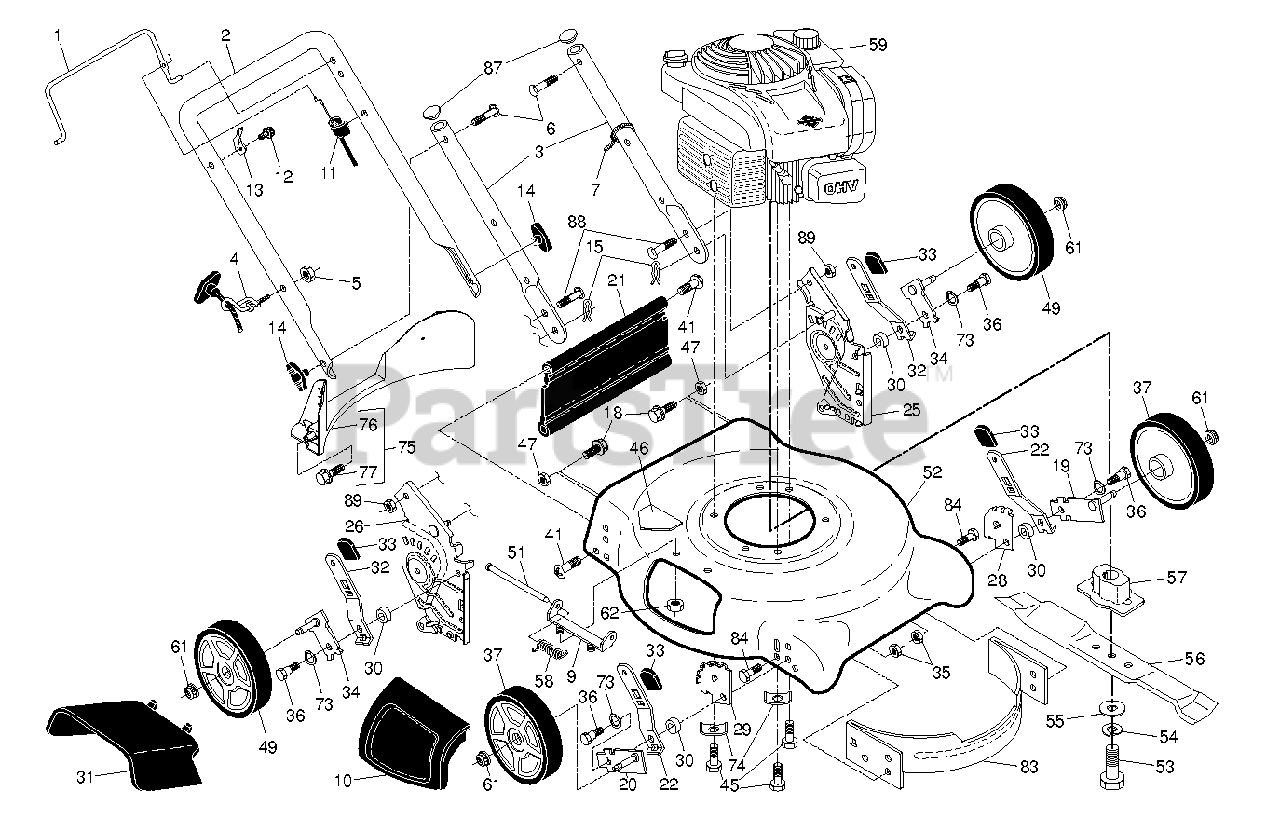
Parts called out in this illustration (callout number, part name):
1	BAIL.CONT.D.STRAIGHT.PUSH.BLK
2	HANDLE.UPPER.ECONOMY.BLACK
3	HANDLE.LOWER.DOME.BT.BLACK
4	Rope Guide, Blk Zinc Chrom
5	T-KNOB.NEW ROPE GUIDE
6	BOLT, HANDLE 5/16-18X1.75
7	TIE GUIDE
9	BRACKET.ASM.HOUSING.EZ.MUL
10	MULCH DOOR
11	CABLE.MZR.RATO.22"LOW.
13	BRACKET.UPSTOP.RT
15	HAIRPIN COTTER
18	SCREW 1/4X20
19	AXLE ARM ASSY FRONT LH
20	AXLE ARM ASSY FRONT RH
21	KIT.SKIRT.21 DOMED.W/LIP
22	SELECTOR SPRING, FRONT
25	BRACKET.ASM.HAND.LW.21.LT.BLAC
26	BRACKET.ASM.HAND.LW.21.RT.BLAC
28	BRACKET.ADJ.5.RTAB.LG.HOLE.ABS
29	BRACKET.ADJ.5.LTAB.LG.HOLE.ABS
30	SPACER.HEIGHT.ADJUSTER
31	CLIP ON DISCHARGE GUARD
32	SPRING.SELECTOR.21RD.HTTRT.BZP
34	ARM.ASM.AXLE.REAR.5/9.POS.BZP
35	NUT.FLANGE.HEX.5/16X18.BLACK
36	SHOULDER BOLT 5/16-18
41	SCREW.1/4-20X21/4.HEX.
45	BOLT 3/8-16X1-1/8
46	No Step Decal
47	NUT.CENTERLOCK.5/16-
49	FENDER.550.LT.W/SFT.W/O.CUP
51	ROD.HINGE.COMBI-C
52	KIT.HSG.21SD.PUSH.MS428.TRI
53	BOLT.3/8-24X1.25 GR8
55	WASHER,HARDEN
56	BLADE.21.PUSH/RWGD/FWGD
57	ADAPTOR.BLADE.7/8
58	TORSION SPRING
61	NUT.HEX.FLANGE.3/8-16.LOCKNUT
62	LOCKNUT.NYLOC.1/4-20
73	WASHER.CURVED.CYLINDRICAL
74	WASHER.ENGINE.BZP
76	BAFFLE.REAR.PLASTIC.21.RD.ECON
77	SCREW.HX.13X.750
83	BAFFLE.FRONT.21.DOME.US
84	BOLT.5/16HEX.WHS.HD
87	PLUG.PLASTIC.7/8".14-20.GAUGE
89	LOCKNUT-FLANGE 5/16-18
